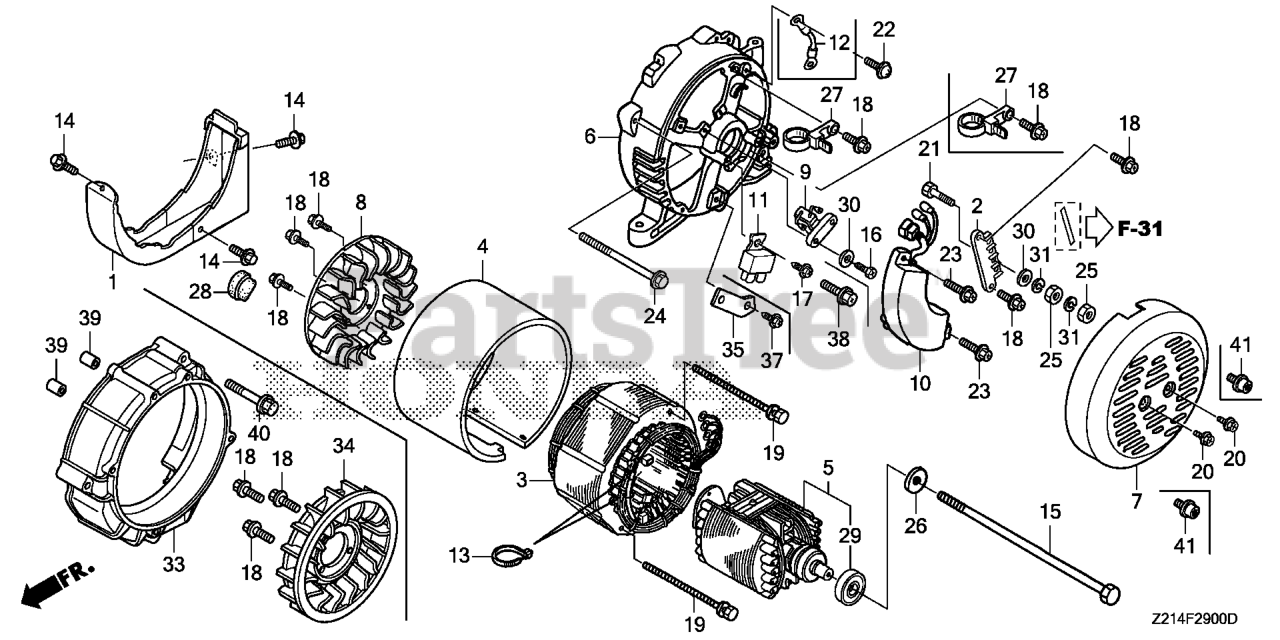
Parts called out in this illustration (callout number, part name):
1	COVER, DUCT
2	TERMINAL, VOLT CHANGE
3	STATOR ASSY.
4	COVER, STATOR *NH105* (MAT BLACK)
6	HOUSING, RR.
7	COVER, GENERATOR END *NH105* (MAT BLACK)
8	FAN, GENERATOR COOLING
9	BRUSH ASSY.
10	REGULATOR ASSY., AUTOMATIC VOLTAGE
11	DIODE, D.C.
13	TIE, CABLE (C)
14	BOLT, FLANGE (5X10)
15	BOLT, HEX. (10X210)
16	SCREW, TAPPING (5X18)
17	SCREW, TAPPING (5X12)
17	SCREW, TAPPING (5X12) (GROUND CABLE)
18	SCREW, TAPPING (5X14)
19	BOLT-WASHER (5X155)
20	SCREW, TAPPING (5X12)
21	BOLT, HEX. (5X20)
22	SCREW, PAN (5X12) (GROUND CABLE)
23	SCREW, TAPPING (5X20)
24	BOLT, FLANGE (6X120)
25	NUT, HEX. (5MM)
26	WASHER (10.5MM)
27	TIE, CABLE
28	GROMMET, CRANKCASE
29	BEARING ASSY. (6204)
30	WASHER, PLAIN (5MM)
31	WASHER, SPRING (5MM)
